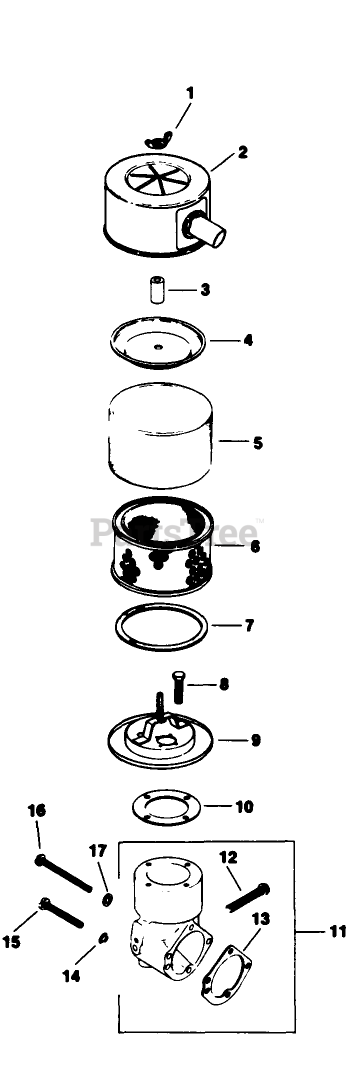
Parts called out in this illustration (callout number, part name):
1	Nut-Wing
2	Cover-Air Cleaner
3	Seal
4	Cover-Inner
5	Precleaner
6	Element
7	Seal
8	Screw-H.C.
9	Base-Air Cleaner
10	Gasket-Air Cleaner
11	Kit-Air Intake Elbow
12	Screw-Self Tap
13	Gasket
14	Washer
15	Screw-R.H.M.
16	Screw-R.H.M.
17	Washer
